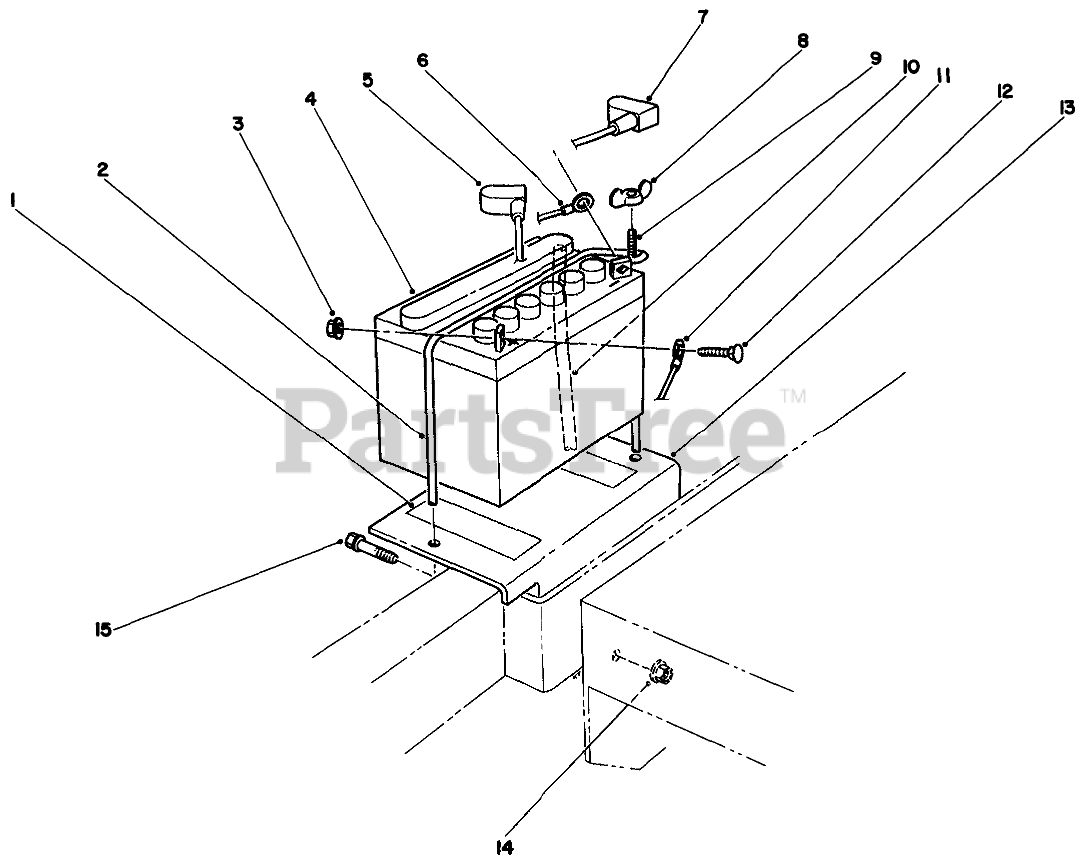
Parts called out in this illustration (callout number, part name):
1	PAD-TANK, FUEL
2	BATTERY CLAMP
3	NUT-KEPS
4	Battery
5	TERMINAL BOOT
6	WIRE ASM
7	BOOT-TERMINAL, RED
8	WING NUT
9	ROD-SUPPORT, BATTERY
10	TUBE-VENT
11	WIRE ASM
12	BOLT-CARR
13	BATTERY BRACKET B
14	NUT-HF
15	SCREW-HHF
